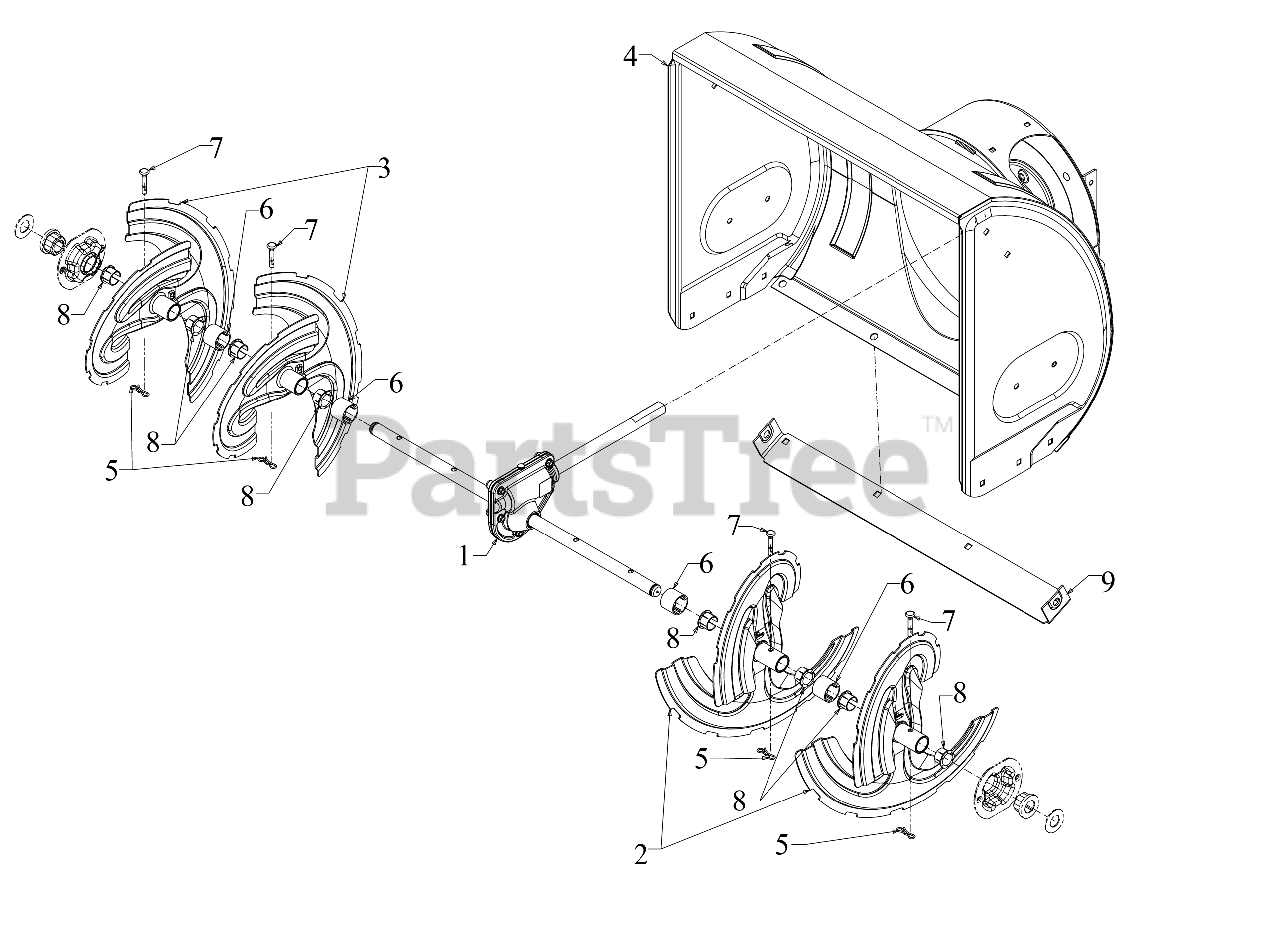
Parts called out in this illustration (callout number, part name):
1	GEARBOX ASSEMBLY 24"
2	10T AUGER SPIRAL (LH)
3	10T AUGER SPIRAL (RH)
5	BOW TIE COTTER PIN 1/4-5/16
6	SPACER 1.25OD x .75ID X1.00 LG
7	SHEAR PIN .25 x 1.50 GR2
7	Cub Cadet SHEAR PINS (2X SNOW)
7	SHEAR PINS QTY 4
8	FLANGE BUSHING
